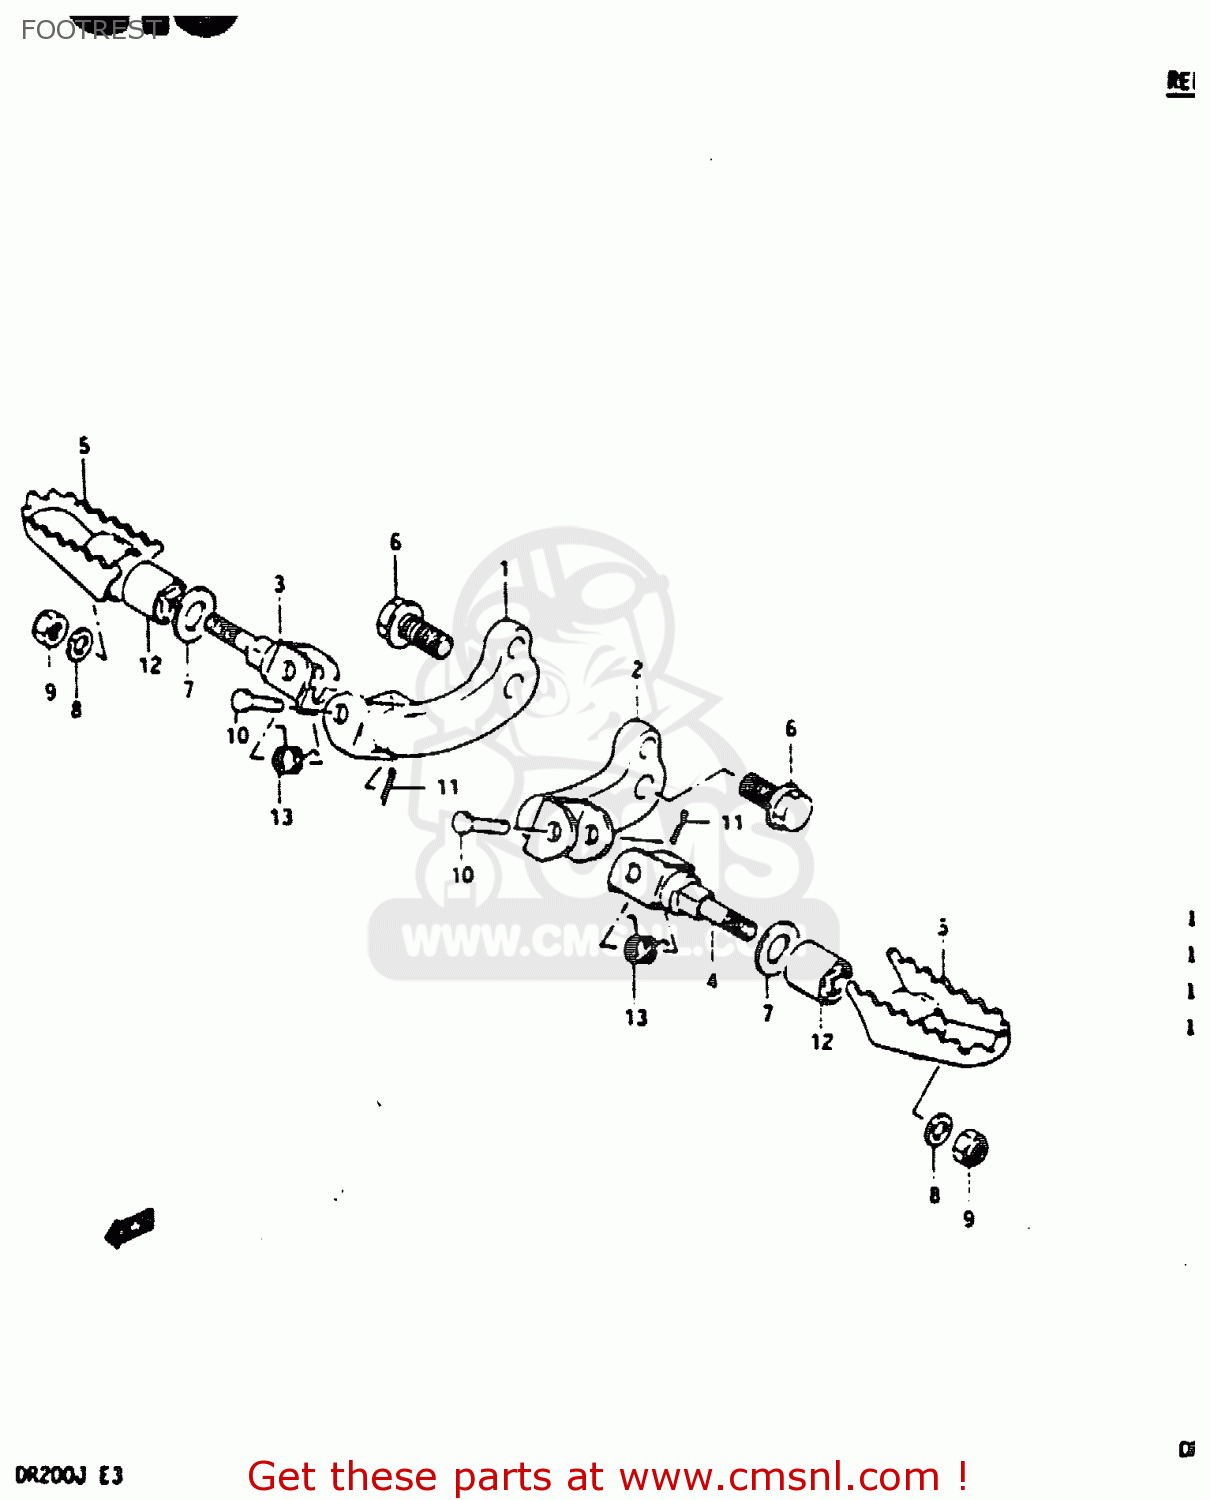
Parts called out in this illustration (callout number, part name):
1	BAR,FRONT FOOTREST
2	BAR,FRONT FOOTREST,LEFT
3	BRACKET,FRONT FOOTREST
4	HOLDER COMP,FRONT FOOT
5	FOOTREST,FRONT
6	BOLT
7	WASHER
8	WASHER,LOCK
9	NUT
10	PIN
11	PIN
12	BUSH
13	SPRING
